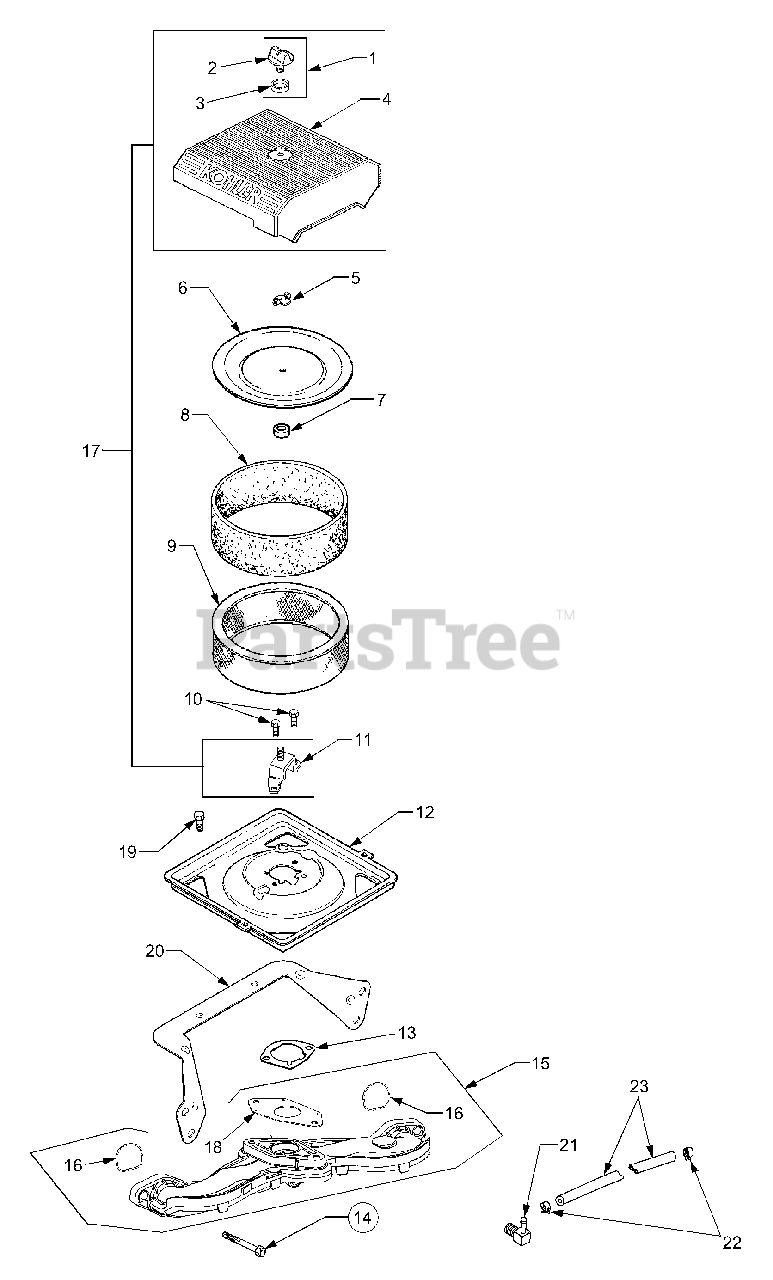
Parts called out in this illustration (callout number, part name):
1	Kit, Knob w/Seal
3	Seal, Air Cleaner Cover Knob
4	Cover, Air Cleaner
6	Cover, Inner Air Cleaner
7	Seal, Inner Air Cleaner
8	Precleaner, Element
9	Element, Air Cleaner
10	Screw, Hex Flange, M6 x 1.0 x16
11	Bracket, Air Cleaner Base
12	Base, Air Cleaner
13	Gasket, Air Cleaner Base
14	Screw, Hex Flange, M6 x 1.0 x 40
15	Manifold, Intake
16	O-Ring, Intake Manifold
17	Kit, Air Cleaner Cover
18	Gasket, Carburetor
19	Screw, Hex Flng, M5 x 0.8 x 10
20	Bracket, Air Cleaner Base
21	Connector, Hose 90°.
22	Clamp, Hose
23	Line, Fuel 17"
